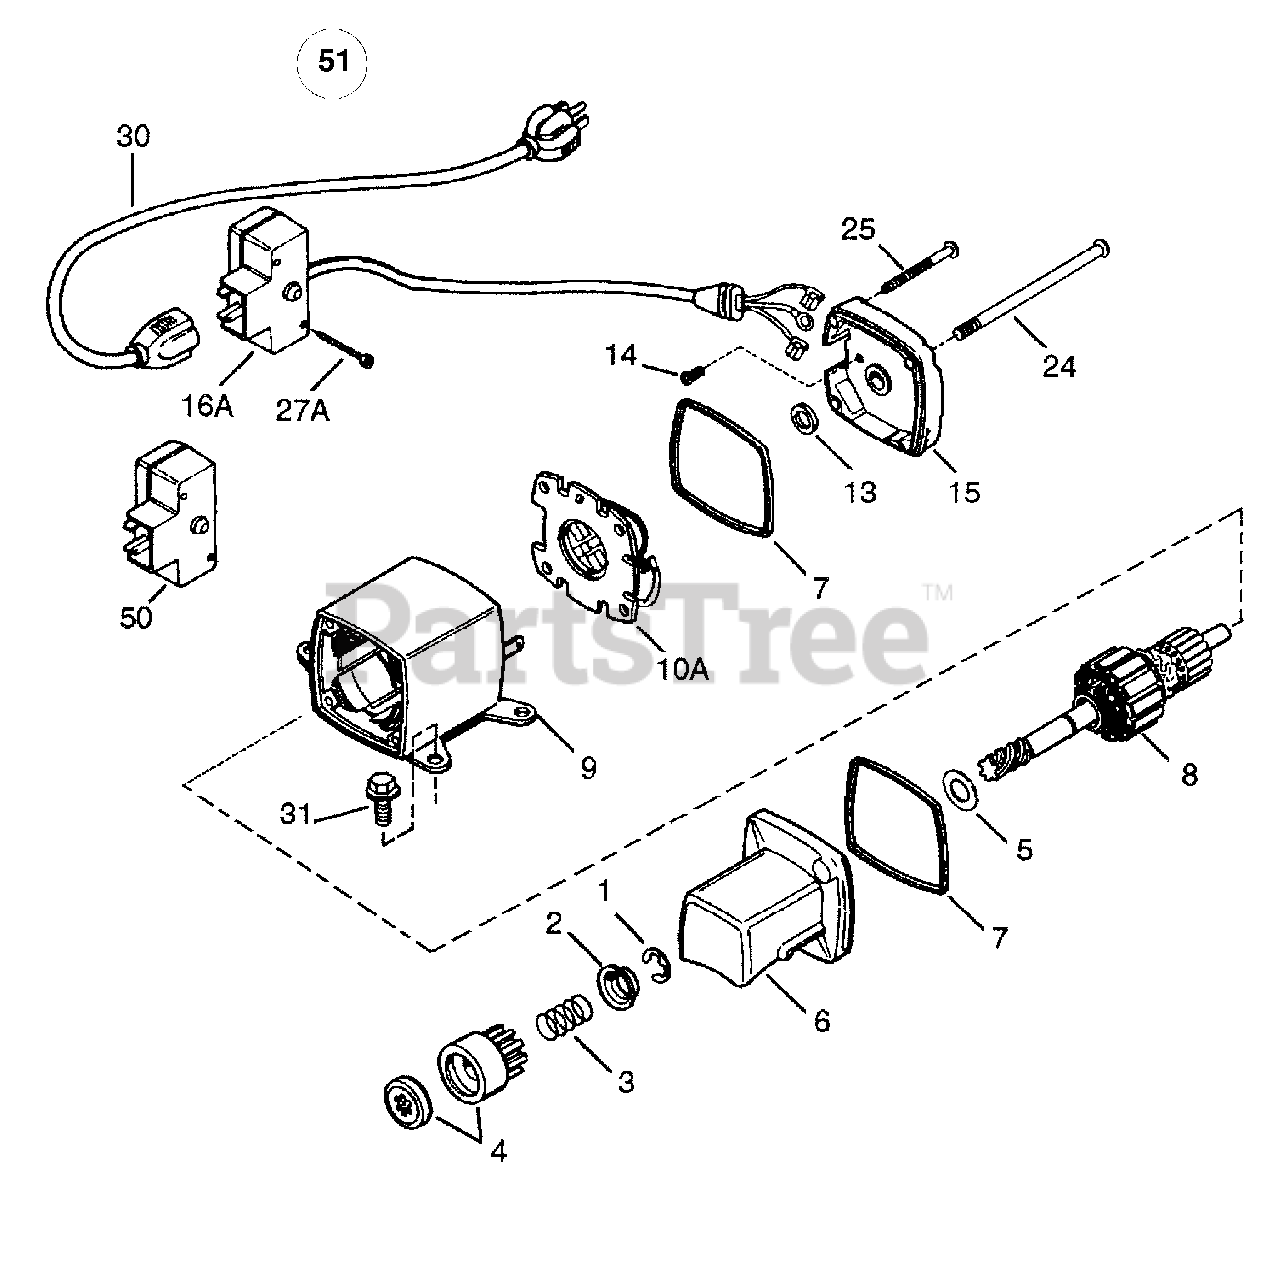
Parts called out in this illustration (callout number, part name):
1	Retainer Ring
2	Spring Retainer
3	Anti-Drift Spring
4	Nut & Gear
5	Thrust Washer
6	Drive End Cap Ass'y
9	Housing Ass'y
10A	Brush & Spring Card Ass'y
13	Thrust Washer
14	Ground Screw
15	Commutator End Cap Ass'y
16A	Switch Box Ass'y
24	Case Bolt
25	Grounding Screw
27A	Screw, 6-32 x 2-1/2"
30	Extension Cord (10' 6")
31	Screw, Torx T-30, 1/4-20 x 23/32"
50	Switch Repair Kit
51	Electric Starter (110 Volt)
